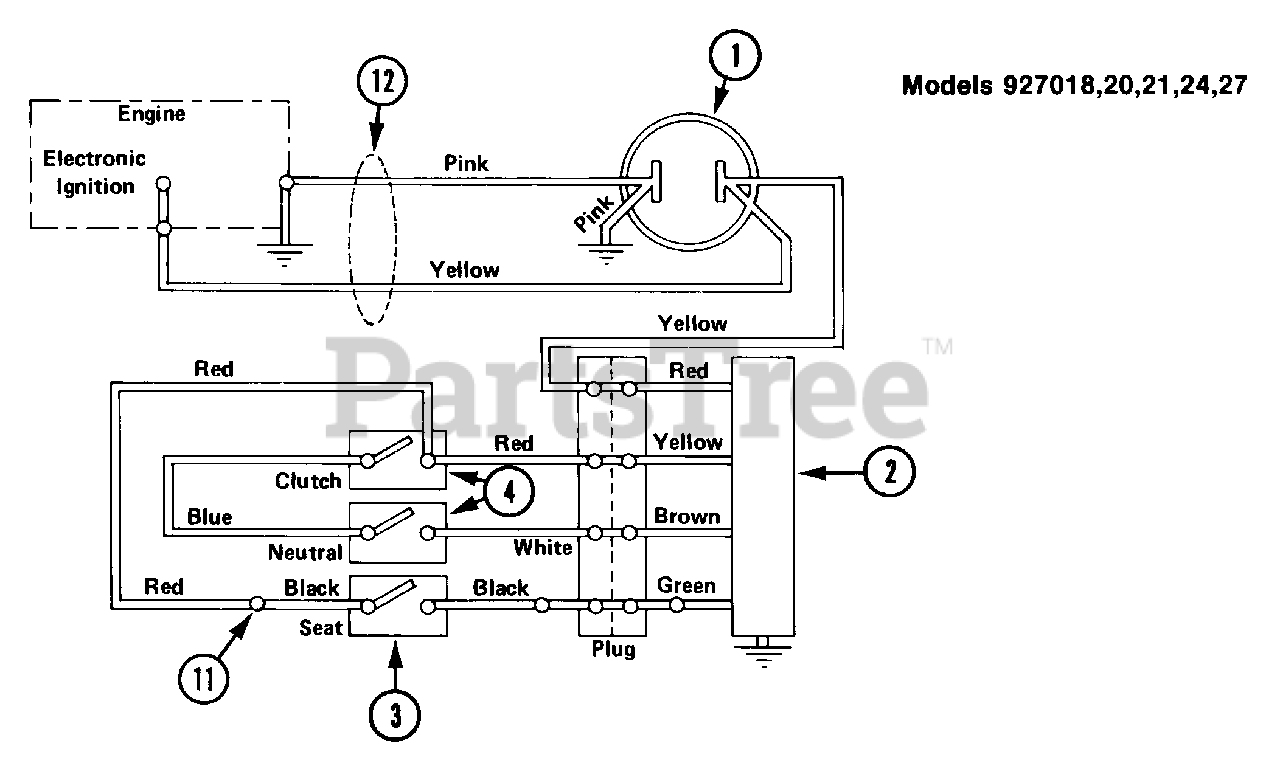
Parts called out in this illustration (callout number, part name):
1	IGNITION SWITCH ASSEMBLY
2	MODULE
3	SAFETY SWITCH
3	SEAT WITH SWITCH REPLACEMENT P
3	SWITCH SEAT
4	SWITCH INTERLOCK
11	ADAPTER - SEAT SWITCH
12	WIRE HARNESS
